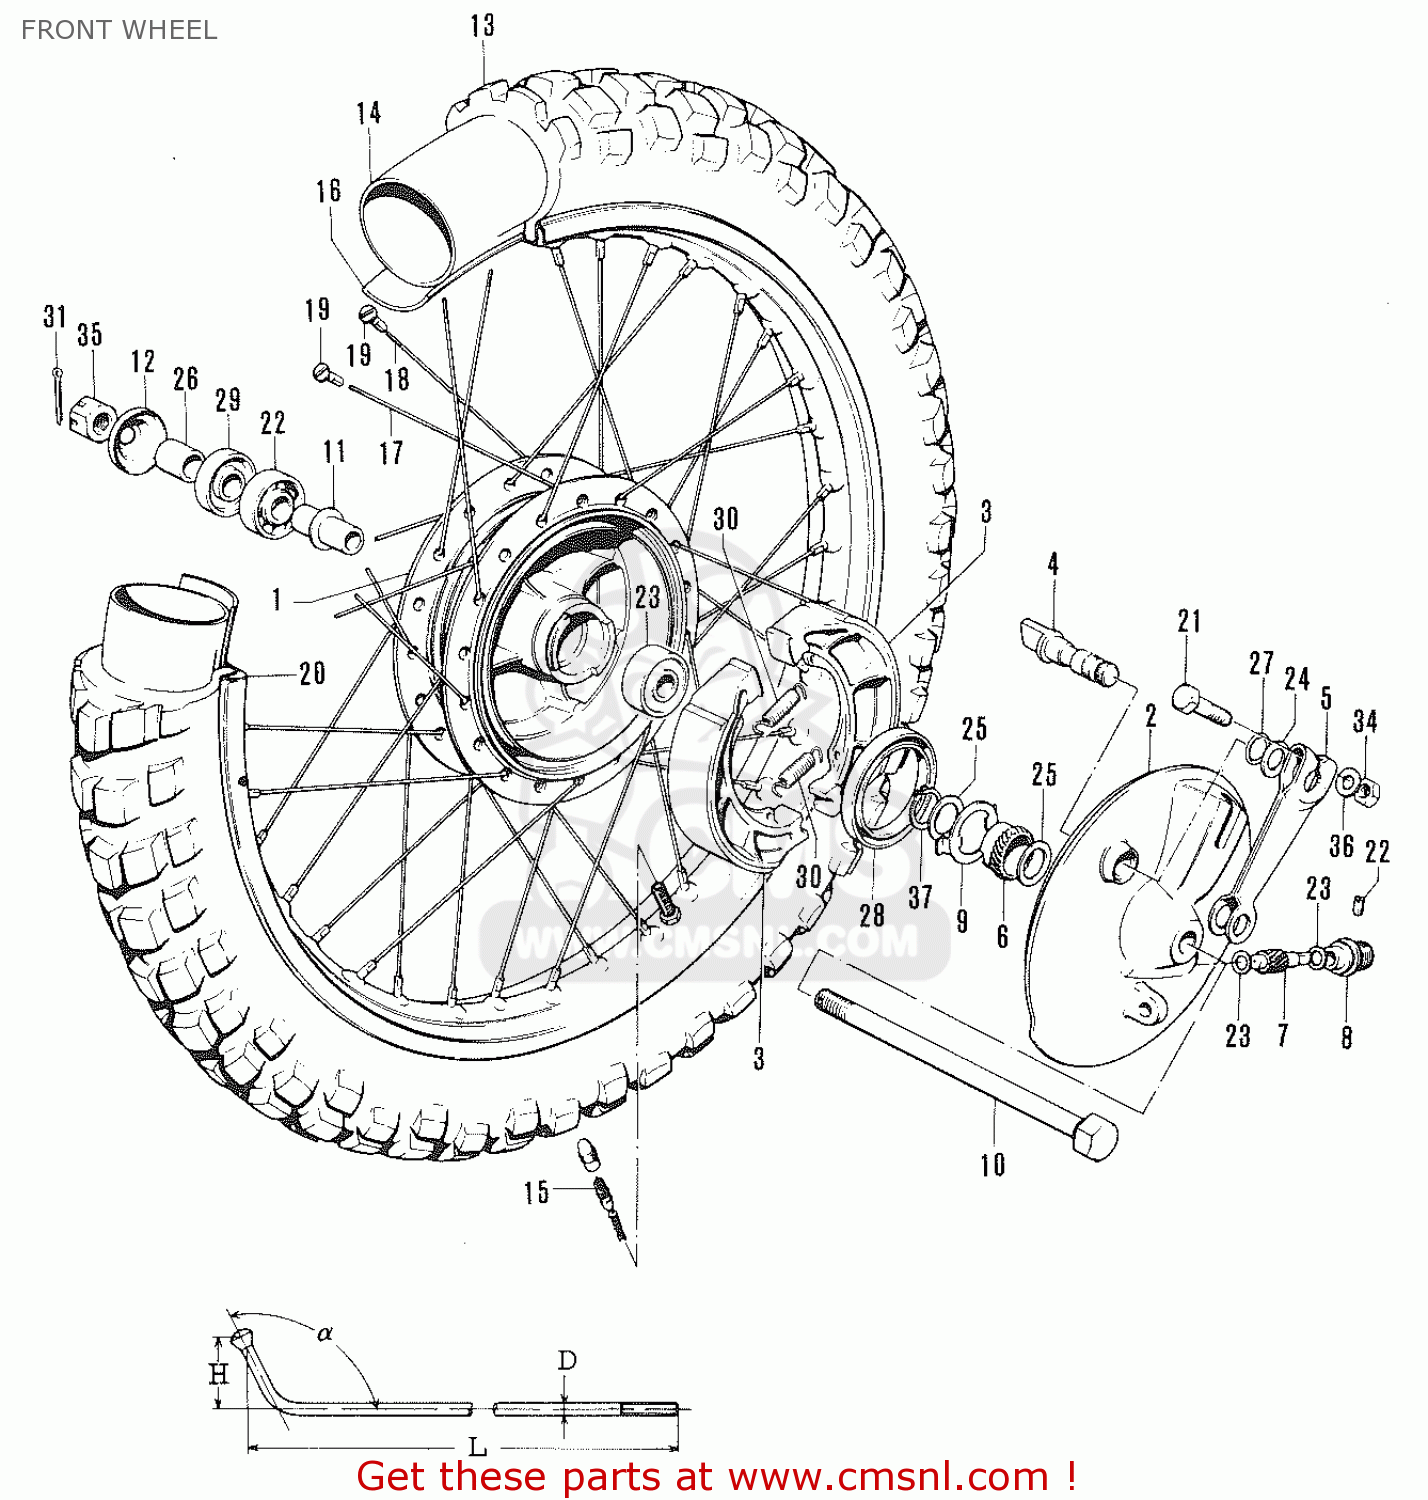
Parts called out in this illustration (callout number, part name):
1	HUB,FRONT
2	PANEL,FRONT BRAKE ANCHOR
3	SHOE,BRAKE
4	CAM,FRONT BRAKE
5	LEVER,FRONT BRAKE CAM
6	GEAR,SPEEDOMETER
7	PINION,SPEEDOMETER
8	BUSH,METER GEAR OUTER
9	DRIVER,SPEEDOMETER GEAR
10	AXLE,FRONT
11	SPACER,FRONT HUB BEARING
12	COVER,FR HUB DUST SEAL
13	TIRE,FRONT
14	TUBE,INNER
15	VALVE,INNER TUBE
16	SPOKE SET,FRONT
17	SPOKE,WHEEL
18	SPOKE,WHEEL
19	NIPPLE,SPOKE
20	RIM,REAR WHEEL
21	BOLT
22	SCREW
23	WASHER (5.1X9X0.4)
24	WASHER(12.5X20X1)
25	WASHER(18.5X24X1)
26	SPACER(12X18X19.4)
27	O RING(D:2.5,ID:11.4)
28	OIL SEAL
29	OIL SEAL(17X38X5)
30	SPRING(L:34)
31	PIN
32	BEARING
33	BEARING, RH
34	NUT
35	CASTLE NUT
36	WASHER
37	CIRCLIP
